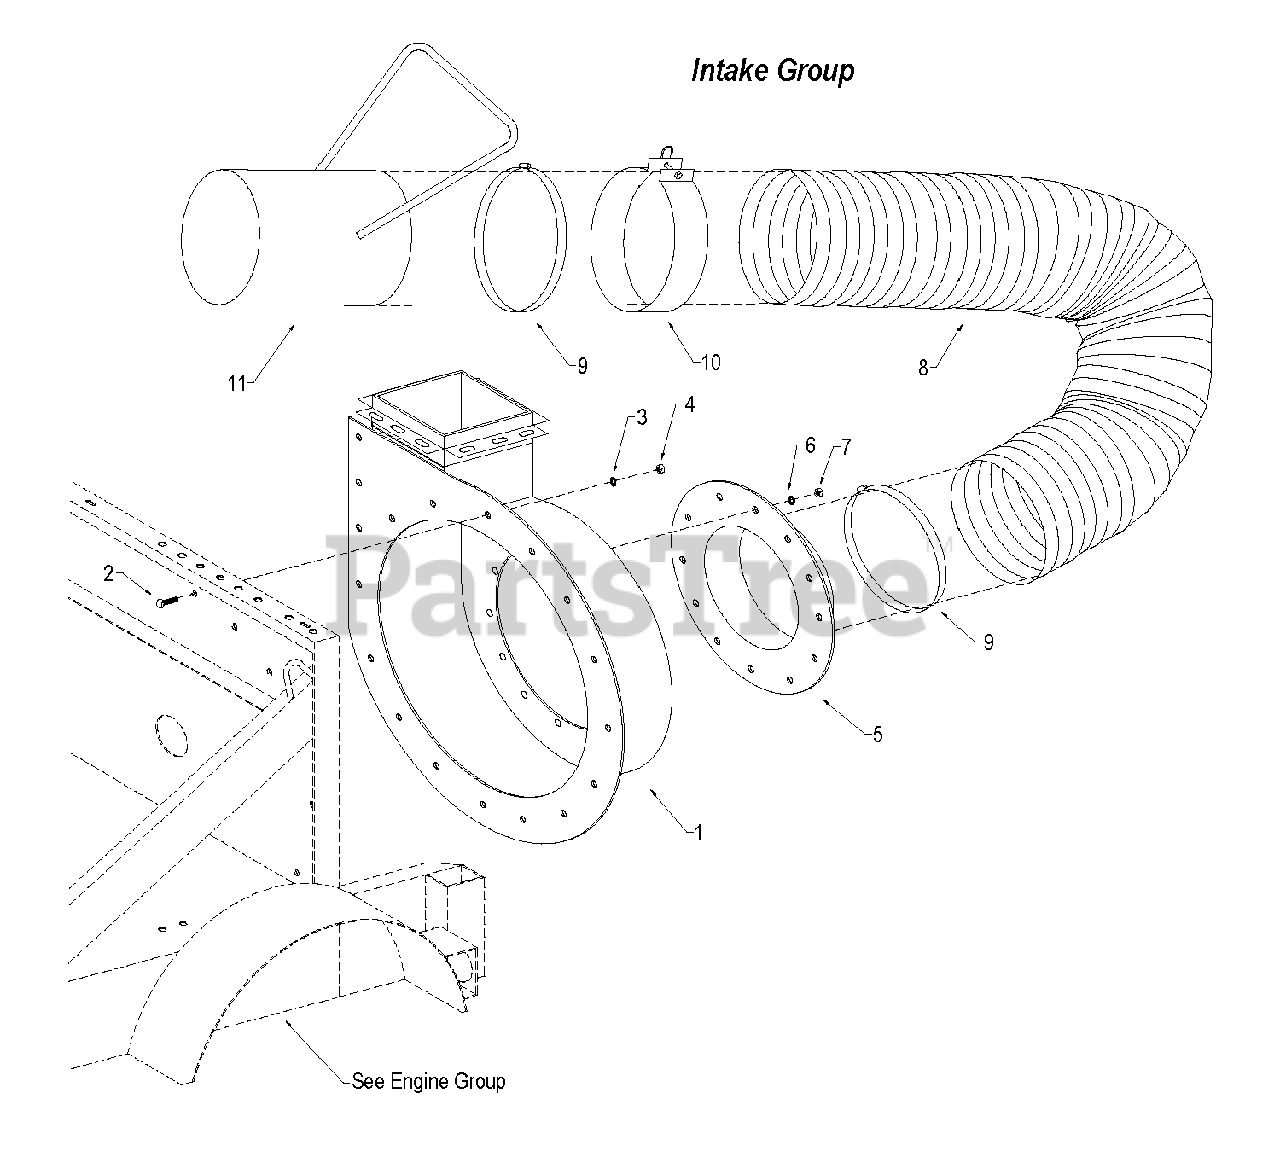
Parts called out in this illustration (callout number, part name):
1	Housing, impeller – complete with liner kit below
2	Bolt, hex - 1/2-13 x 1-1/4"
3	Washer, lock - 1/2"
4	Nut, hex - 1/2-13
5	Flange, intake, 18 straight (skid version)
5	Flange, intake, 18 90 degree (CHW version)
6	Washer, lock - 1/2
7	Nut, hex - 1/2-13
8	Hose, intake - 18" x 8'
9	Clamp, hose - 18"
10	Band, hose support – 18 – with hardware *
11	Nozzle, intake - 18"
